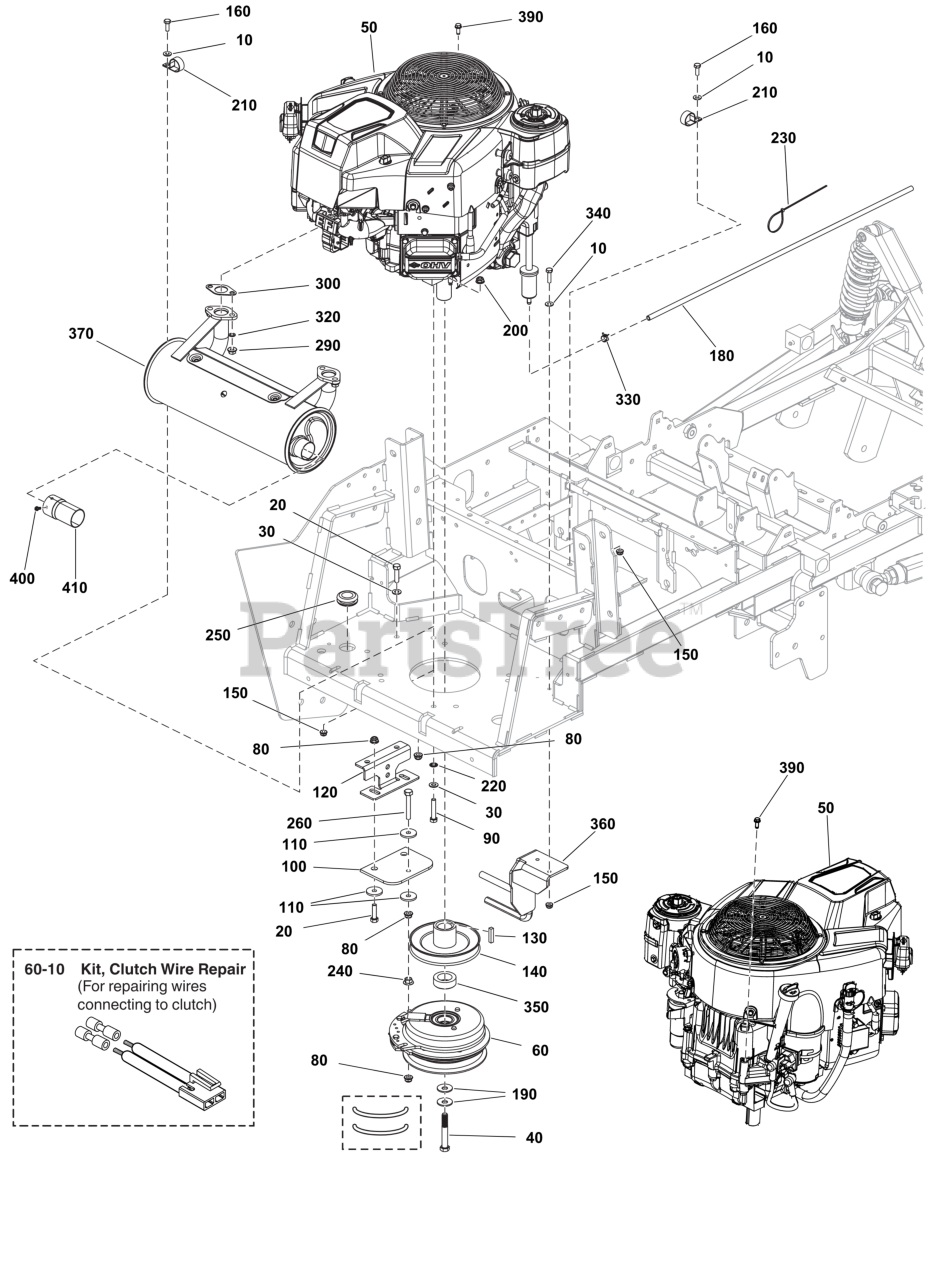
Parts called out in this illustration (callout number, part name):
10	WASHER
30	WASHER
40	BOLT, CRANKSHAFT, 7/1
60-10	KIT, CLUTCH WIRE REPAIR
80	NUT
90	BOLT
100	CLUTCH ANCHOR PAD
110	WASHER, .34 X 1.25 X
120	ANCHOR, CLUTCH
130	KEY, 1/4 SQ X 1-1/4
140	PULLEY, Crankshaft
160	BOLT, 1/4-20 X 3/4" G
180	HOSE, 1/4" FUEL, 29.00"
190	BELLEVILLE WASHER
220	WASHER, 5/16" INT. TO
230	TIE,SELF-LOCKING, 24"
240	NUT, 5/16-18 HEX SERR
250	GROMMET, 7/8"ID
260	BOLT, 5/16-18 X 2-1/4
300	GASKET, Exhaust
320	WASHER, 5/16 LIGHT LO
330	CLAMP, Hose
340	BOLT, 1/4-20 X 1", GD
360	GUIDE, Belt
370	MUFFLER, RIGHT OUTLET
390	SCREW, 1/4-20X0.625
400	SCREW,SELF-TAP,#8-32
410	EXTENSION, TAILPIPE
